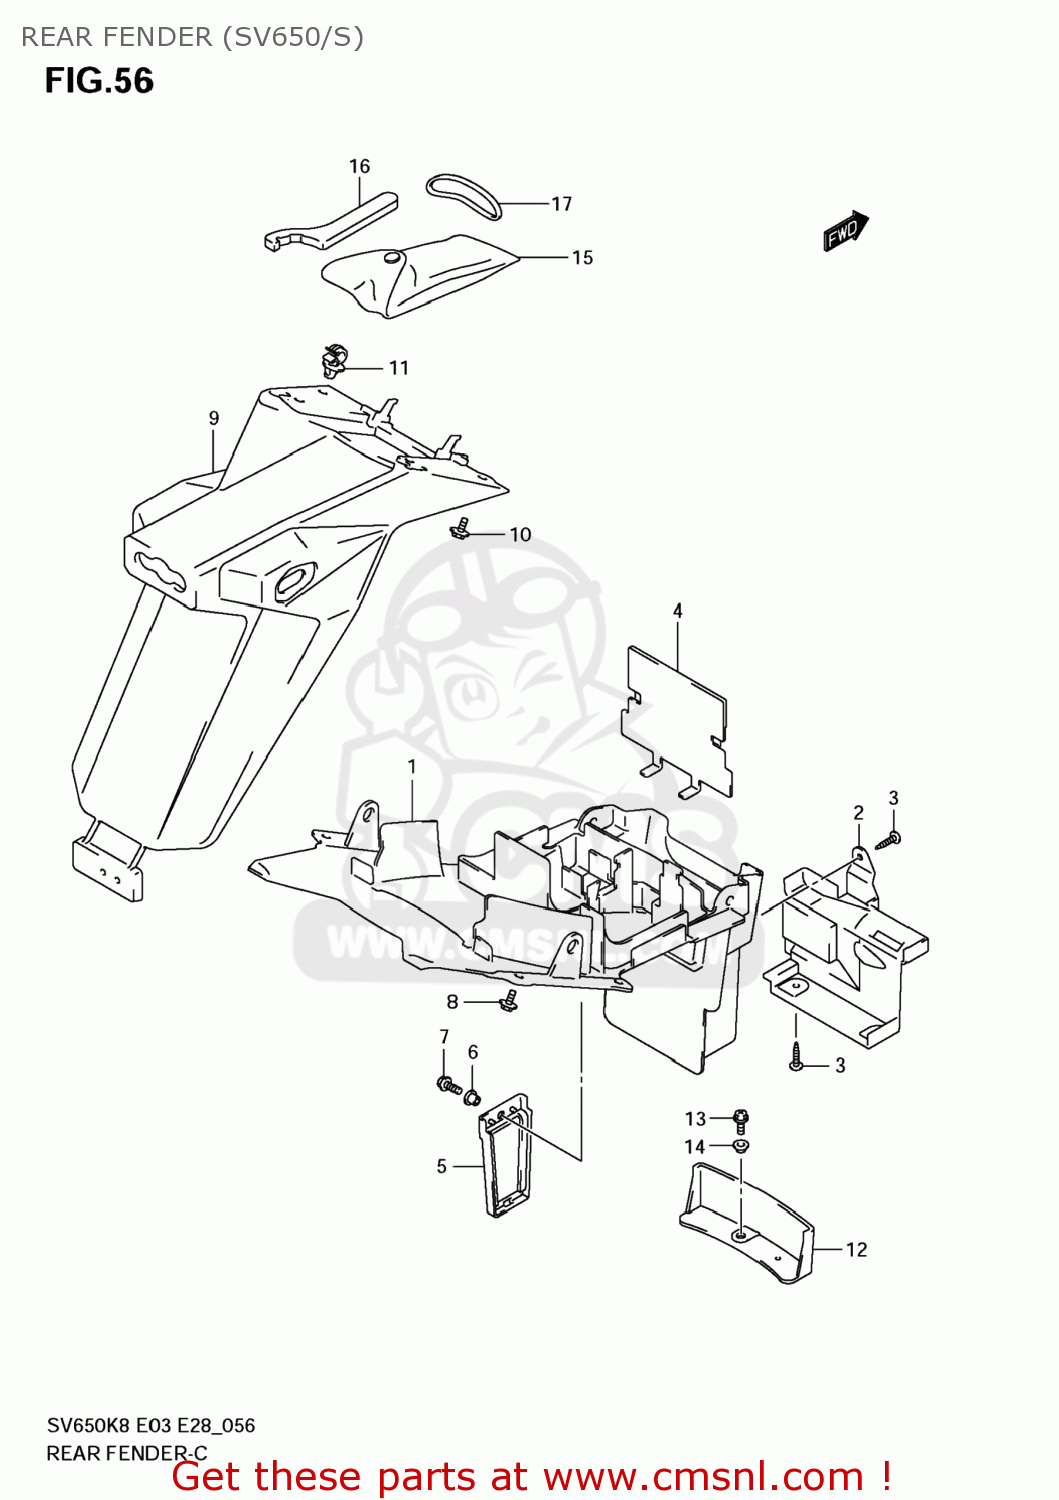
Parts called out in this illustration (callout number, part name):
1	FENDER,RR FR
2	COVER,RR FENDER FR
3	SCREW
4	COVER,RR FENDER UPR
5	LID,RR FENDER FR
6	GROMMET
7	PLUNGER
8	BOLT(6X12)
9	FENDER,RR RR
10	BOLT(6X12)
11	CLAMP
12	MUDGUARD,RR FENDER LWR
13	SCREW
14	WASHER
15	TOOL ASSY
16	CLAMP
17	O RING(D:3.5,ID:61)
